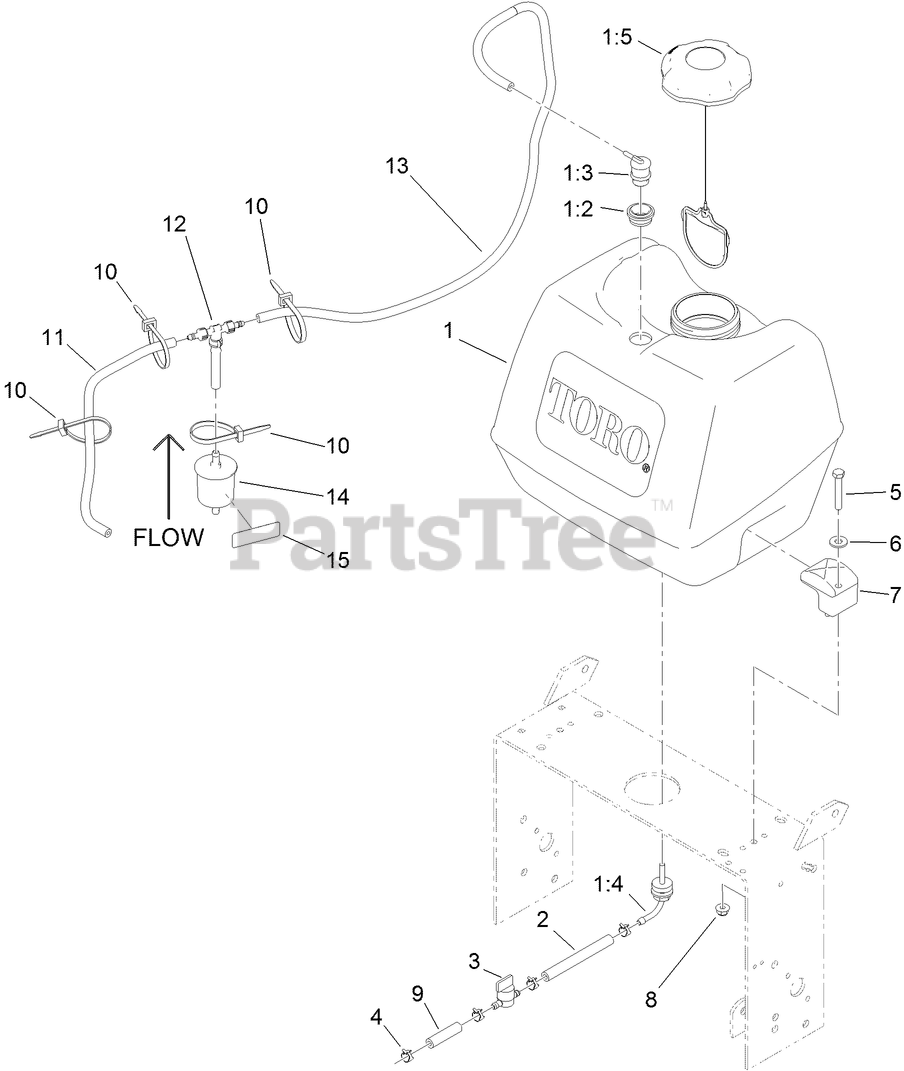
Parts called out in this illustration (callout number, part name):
1	FUEL TANK ASM
1:2	GROMMET
1:3	VALVE-VENT, FUEL
1:4	FITTING-FUEL, BULKHEAD
1:5	CAP-FUEL, RATCHETING
2	HOSE-FUEL
3	VALVE-FUEL
4	CLAMP-HOSE
5	SCREW-HH
6	WASHER-FLAT
8	NUT-HF, NI
9	HOSE-FUEL
10	TIE-CABLE
11	HOSE-FUEL
12	TEE AND CHECK
13	HOSE-EMISSIONS
14	FILTER-FUEL
15	DECAL-FILTER, EMISSIONS
